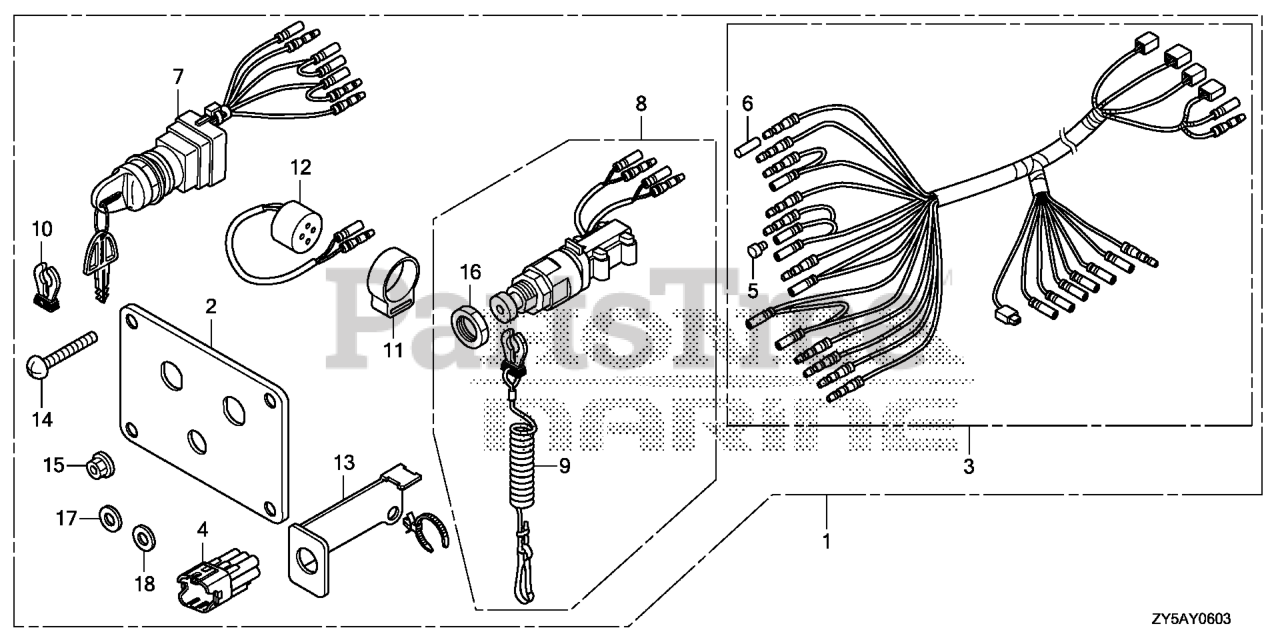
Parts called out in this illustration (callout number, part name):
1	PANEL KIT, SWITCH (TWIN)
1	PANEL KIT, SW
2	PANEL, CONTROL (TWIN)
3	HARNESS ASSY., SWITCH PANEL
4	DUMMY, WATERPROOF CONNECTOR (GREEN)
5	PLUG, CONNECTOR (INNER) (TROLLING CONTROL)
6	PLUG, CONNECTOR (OUTER) (ENGINE NO.)
7	SWITCH ASSY., COMBINATION
8	SWITCH ASSY., EMERGENCY STOP (TWIN)
9	WIRE, EMERGENCY
10	CLIP, EMERGENCY LOCK
11	SUSPENSION, AUDIBLE PILOT
12	BUZZER, WARNING
13	BRACKET
14	SCREW, PAN (5X40) DUAL QTY = (8) (SINGLE)
15	NUT, FLANGE (5MM)
16	NUT
17	WASHER, PLAIN (5MM)
18	WASHER, SPRING (5MM)
18	WASHER, SPG (5MM)
